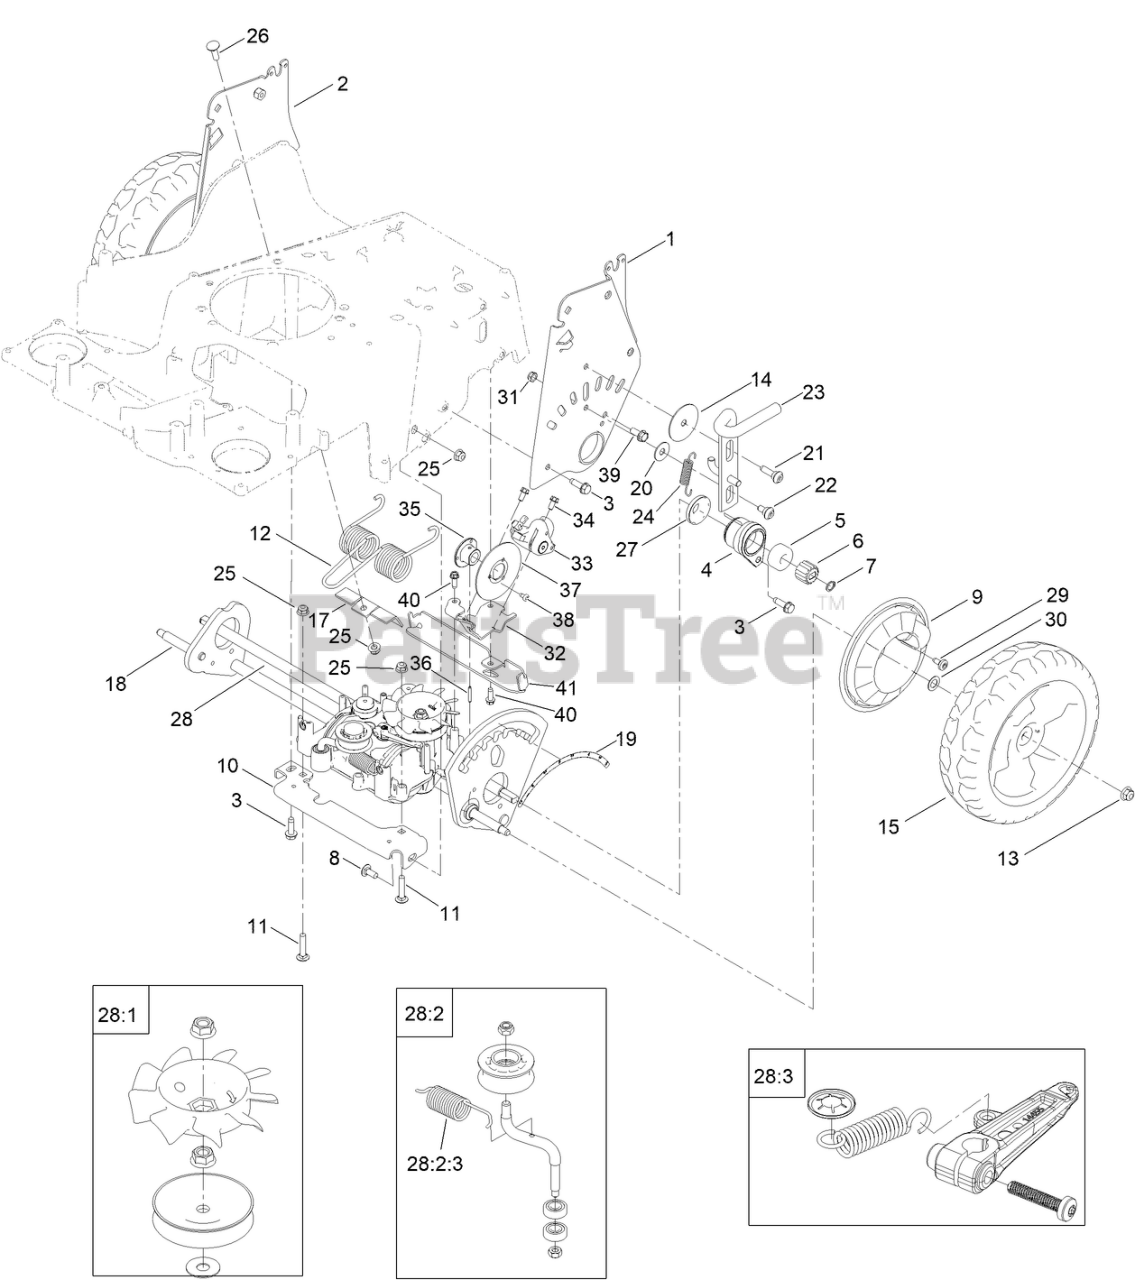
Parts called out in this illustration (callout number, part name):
1	HOC PLATE ASSEMBLY
2	HOC PLATE ASSEMBLY
3	SCREW-THD ROLL, HWH
4	BEARING RETAINER ASM
5	BEARING-BALL, CUSTOM
6	GEAR-PINION, 15T
7	RING-RETAINING
8	SCREW-CARR
9	COVER-WHEEL
10	BRACKET-TRANSMISSION, FRONT
11	BOLT-CARR
12	SPRING-TORSION
13	NUT-HF, NI
14	WASHER-PLAIN
15	10.5 IN. WHEEL ASM
17	BRACKET
18	REAR AXLE ASM
19	DECAL-HOC, REAR
20	WASHER
21	SCREW-SHOULDER, BHTF
22	BOLT-SHOULDER
23	LOCK-HEIGHT, ADJ
24	SPRING-EXTENSION
25	NUT-HF, NI
26	BOLT-CARR
27	COVER-BEARING
28	TRANSMISSION-MV702
28:1	PULLEY FAN REPAIR KIT
28:2	IDLER PULLEY REPAIR KIT
28:2:3	SPRING-TENSION, BELT
28:3	CLUTCH LEVER REPAIR KIT
29	SCREW-SHOULDER
30	WASHER-PLAIN
31	NUT-LOCK, NI
32	BRACKET-MOUNT, BRAKE
33	CALIPER-BRAKE, DISC
34	SCREW-HWH
35	HUB-ROTOR
36	PIN-ROLL
37	DISC-ROTOR
38	SCREW-TORX PH THD ROLL
39	SCREW
40	SCREW-HWHTF
41	BRACKET-SUPPORT, CABLE
